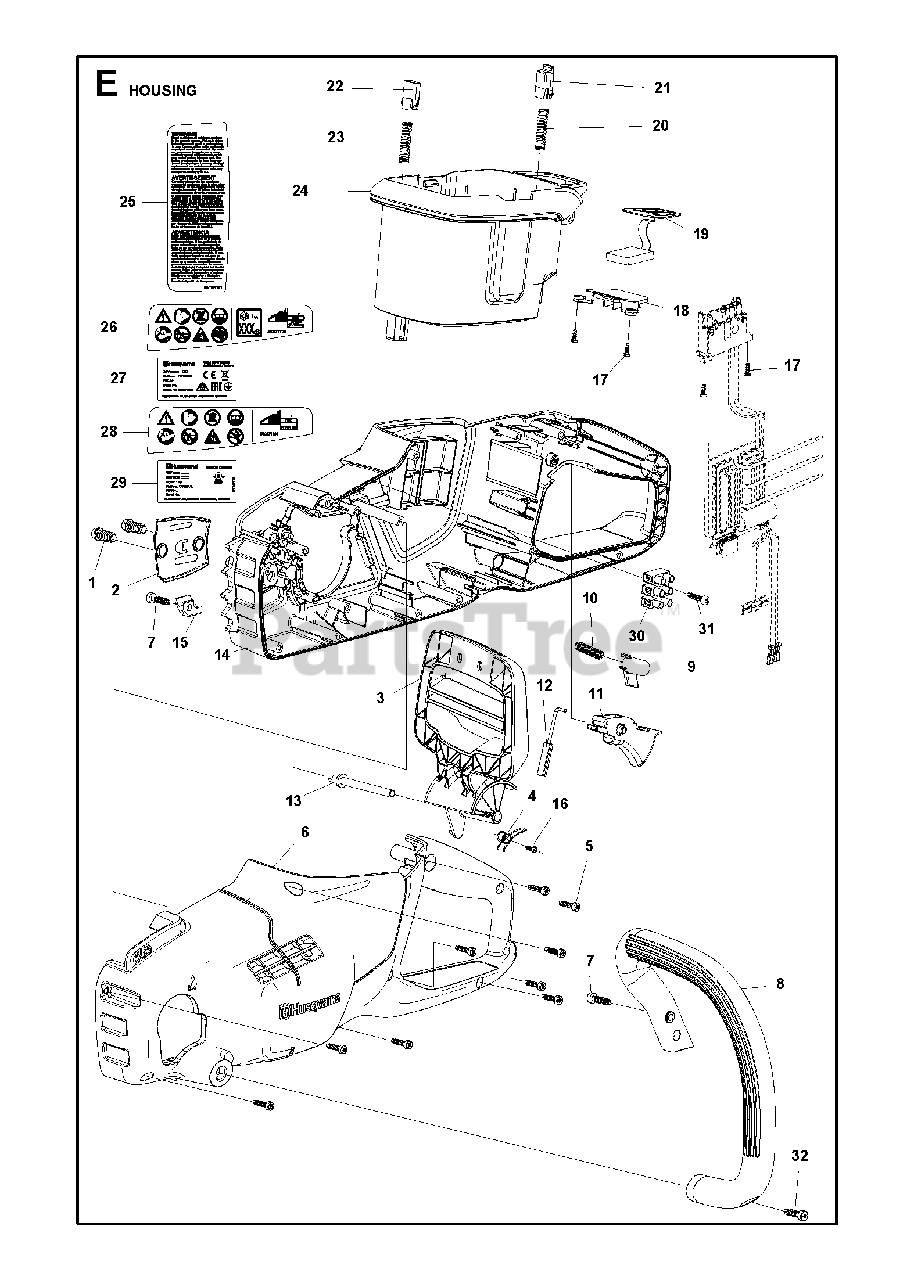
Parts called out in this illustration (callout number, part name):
1	SCREW ST8X16
2	MOUNTING PLATE BAR
3	BRAKE HAND GUARD
4	SPRING BRAKE CUT OFF POWDER
5	SCREW ST4X16
6	HOUSING LEFT PAINTING
7	SCREW ST4.8X18
8	FRONT HANDLE
9	BUTTON LOCK OFF
10	SPRING LOCK OFF BUTTON
12	LEVER TRIGGER
13	PIVOT HAND GUARD
14	HOUSING RIGHT ASSEMBL
15	CHAIN CATCHER
16	SCREW SCREW MT3X10 36V
17	SCREW ST3X8
18	BRACKET KEY PAD
19	KEYPAD CHAINSAW
20	SPRING PUSH BUTTON
21	PUSH BUTTON
22	PUSH BUTTON FRONT
23	SPRING PUSH BUTTON
24	BATTERY BOX
25	LABEL WARNING TEXT, US
26	Warning Decal
27	Decal, Rating
28	Warning Decal
29	Decal, Rating
30	CONNECTOR SMALL
31	SCREW ST3X16
32	SCREW
